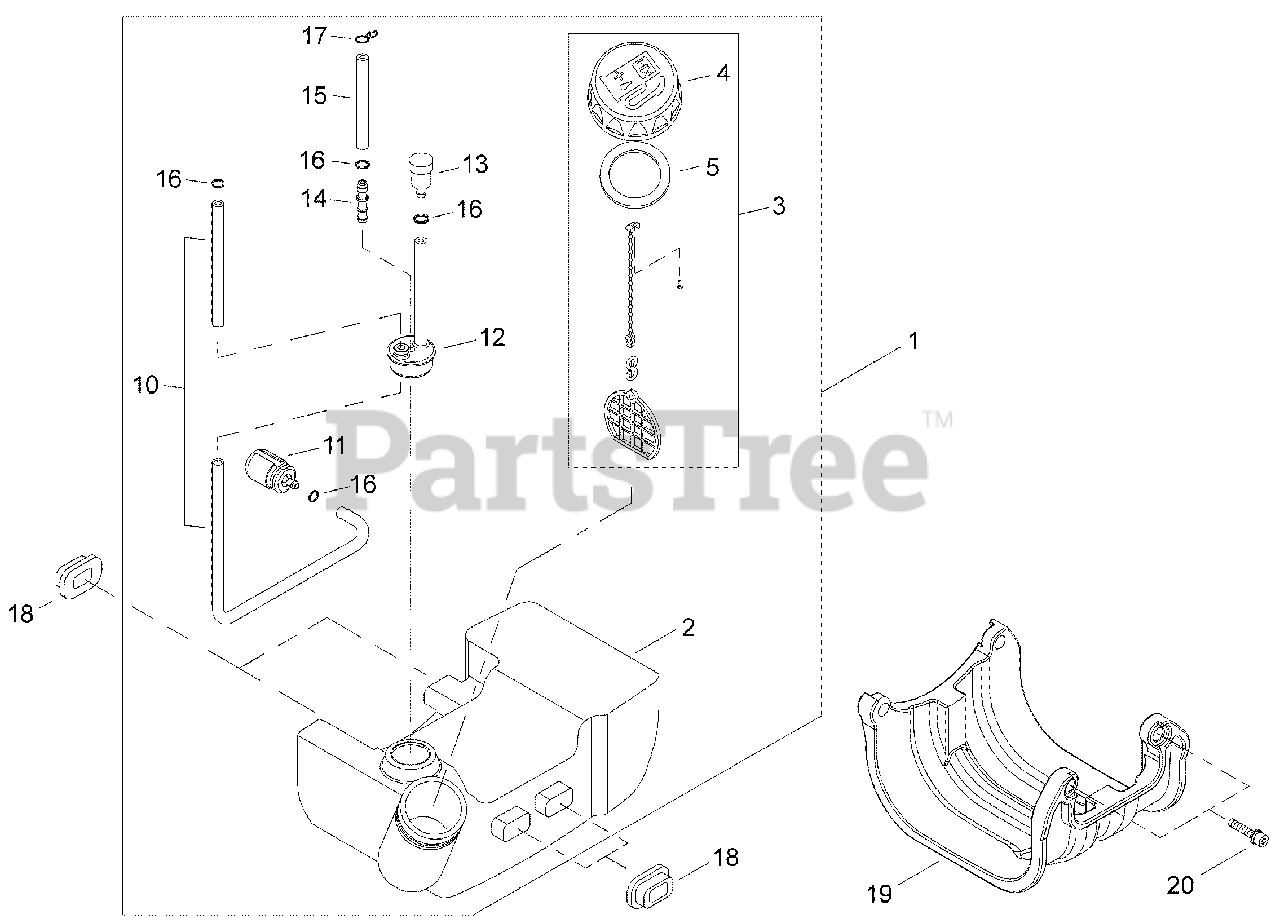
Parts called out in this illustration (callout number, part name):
1	TANK ASSY, FUEL
2	TANK, FUEL
3	CAP ASSY, FUEL
4	CAP, FUEL
5	GASKET, FUEL CAP
10	PIPE, FUEL 3.3×6×160
11	FILTER, FUEL 125-528
12	GROMMET, FUEL W/VENT PIPE
13	VENT ASSY
14	CONNECTOR, PIPE
15	PIPE, FUEL RETURN L= 52.5 MM
16	CLIP Ø6
17	CLIP, SPRING Ø5.2
18	CUSHION, FUEL TANK
19	GUARD, PLASTIC FUEL TANK
20	BOLT M5×20
